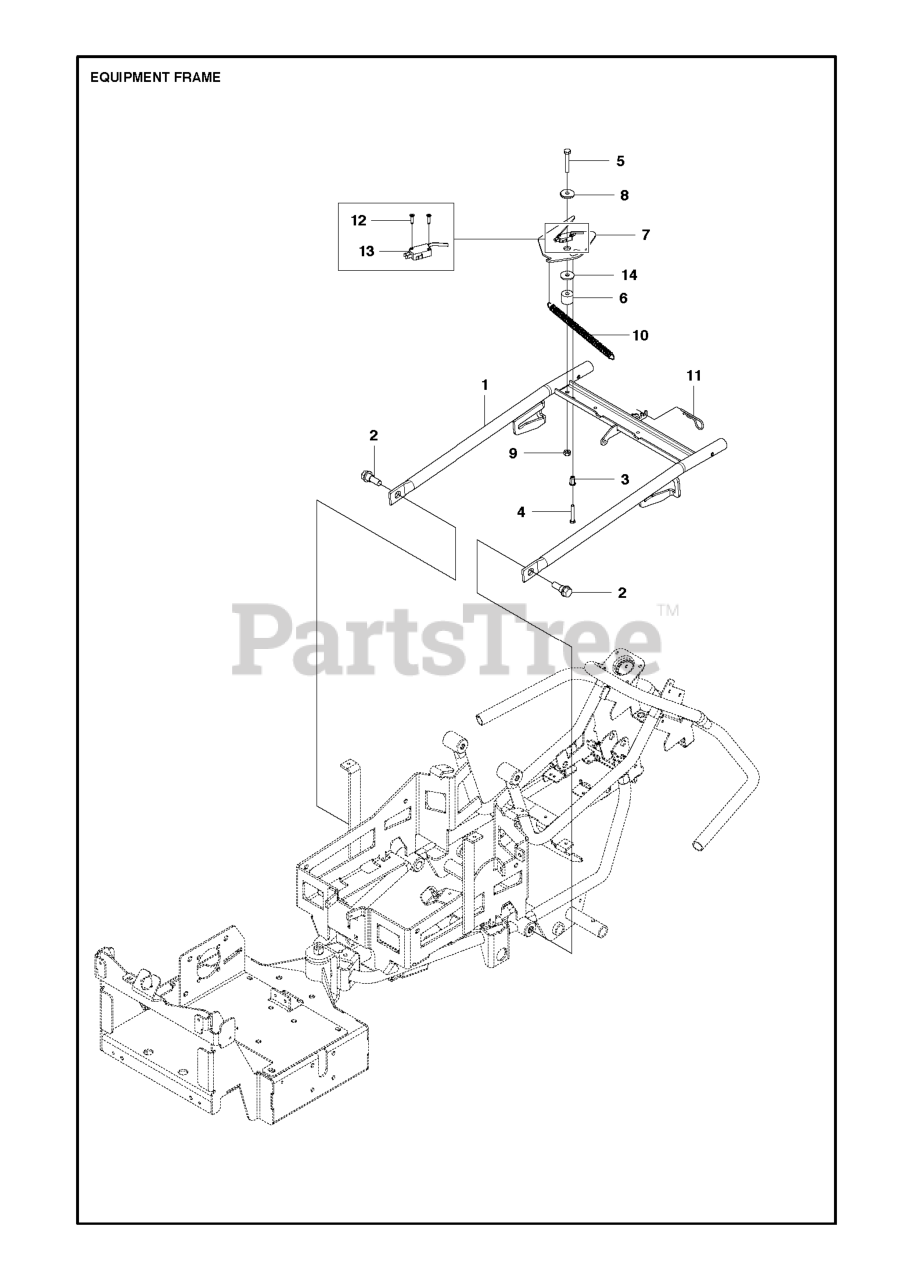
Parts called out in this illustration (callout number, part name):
8	WASHER
9	LOCKNUT M8
13	MICRO SWITCH
